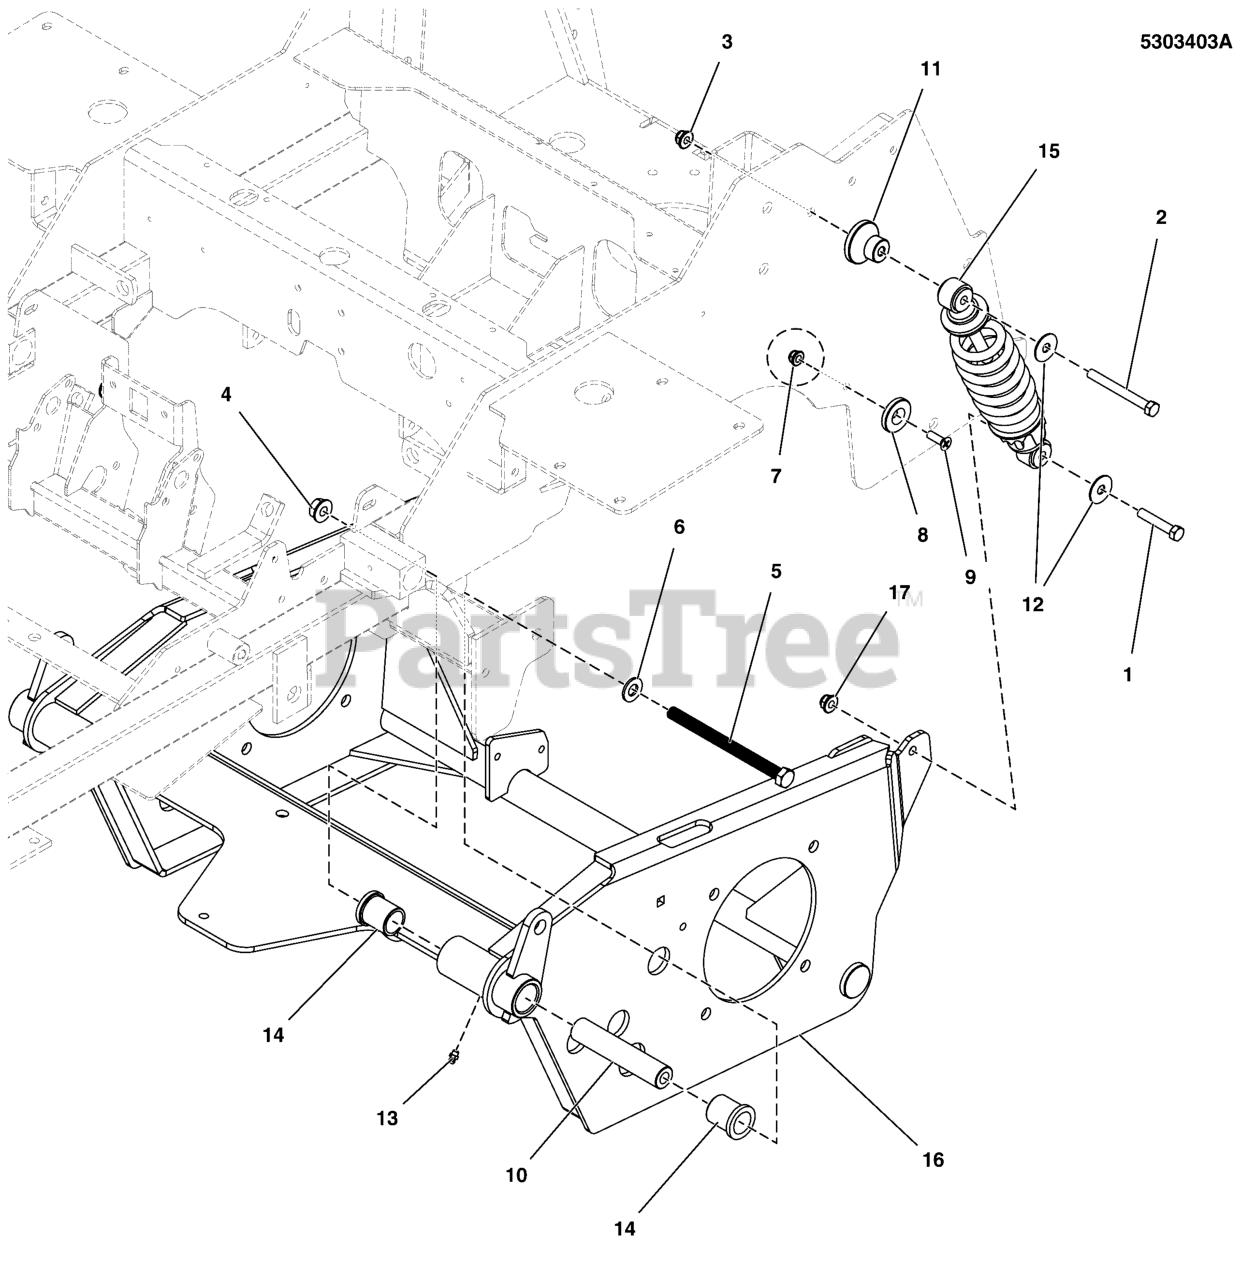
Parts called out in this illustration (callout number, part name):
1	HHCS, 3/8-16 X 2.00, GR5, ZINC/CLEAR
2	BOLT, 3/8-16 X 3-1/2" GD5 CZ
3	NUT, 3/8-16 HEX NYLOCK FLANGE
4	NUT, Hex Flange, Nylock, 1/2-13
5	BOLT, 1/2-13 X 6-1/2 GD8, YZ
6	WASHER, 1/2 SAE
7	NUT, 5/16-18 HEX NYLOCK FLANGE
8	SPACER, .34 X 1.54 X .25, PL
9	SCREW, 5/16-18X1, PHILLIPS HD. BZ
10	SPACER, .52 X 1.00 X 5.00
11	SPACER, .39 X 2.00 X 1.35, PM
12	WASHER-3/8 FENDER
13	GREASE FITTING, 1/4-28 STRAIGHT
14	BUSHING, FLANGE
15	SHOCK / SPRING ASSEMBLY, OE22376
16	CRADLE, Suspension
17	NUT, 3/8 - 16 HEX NYLOCK FLANGE
